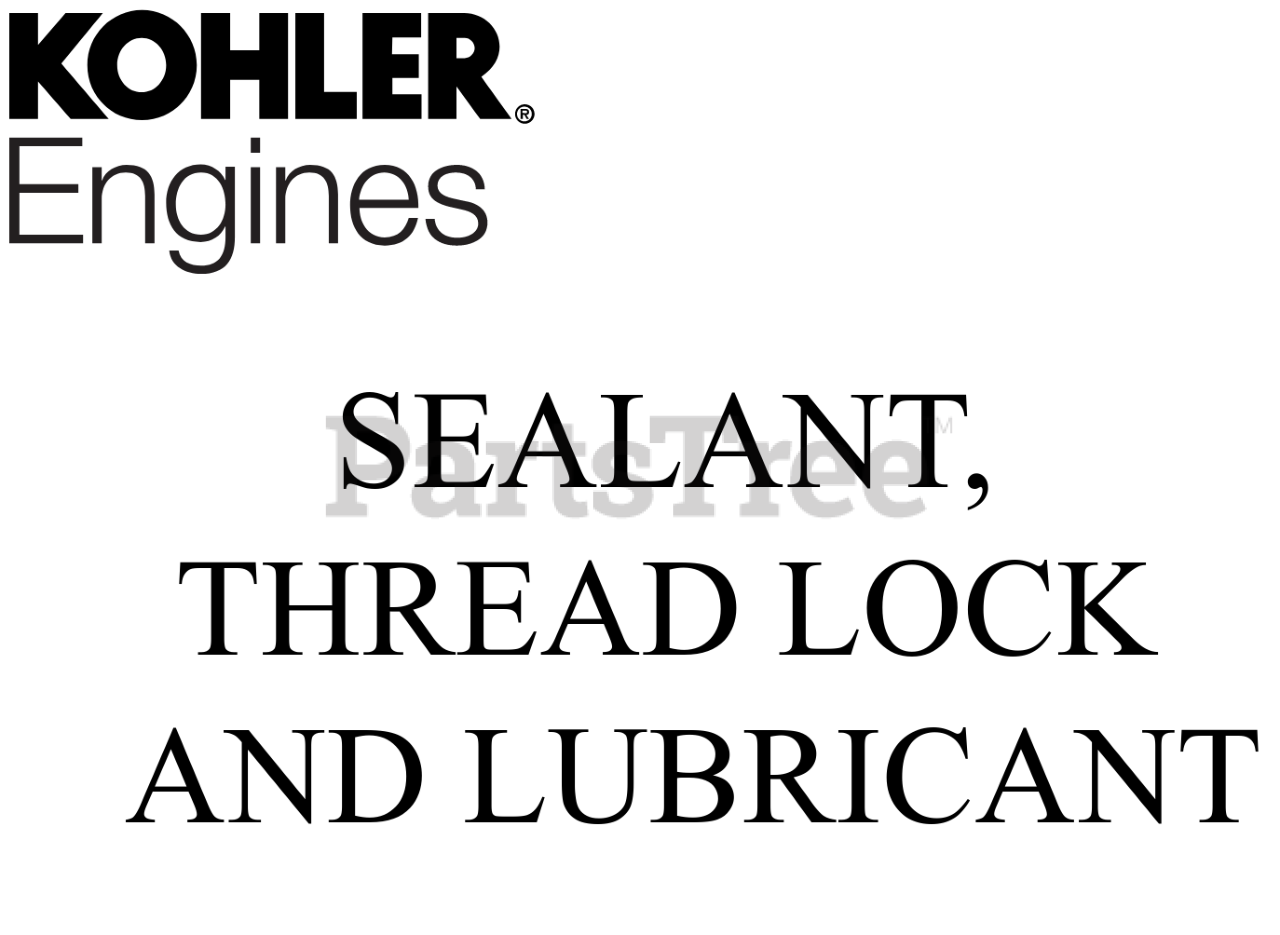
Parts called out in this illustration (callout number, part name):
NI	QUART OF OIL - SAE30
NI	QUART OF OIL - 10W30-USE 25 357 65-S
NI	LUBRICANT, GREASE (SPLINE)
NI	LUBRICANT, CAMSHAFT
NI	20W50 OIL (QUART)-USE 25 357 68-S
NI	SEALANT(LOCTITE 620)-(#2559711S)
NI	SEALANT(LOCTITE 222 RETAIN CMPND 0.5ML)
NI	SEALANT(LOCTITE INSTANT GASKET 4 OZ)
NI	LUBRICANT, BENDIX STARTR
